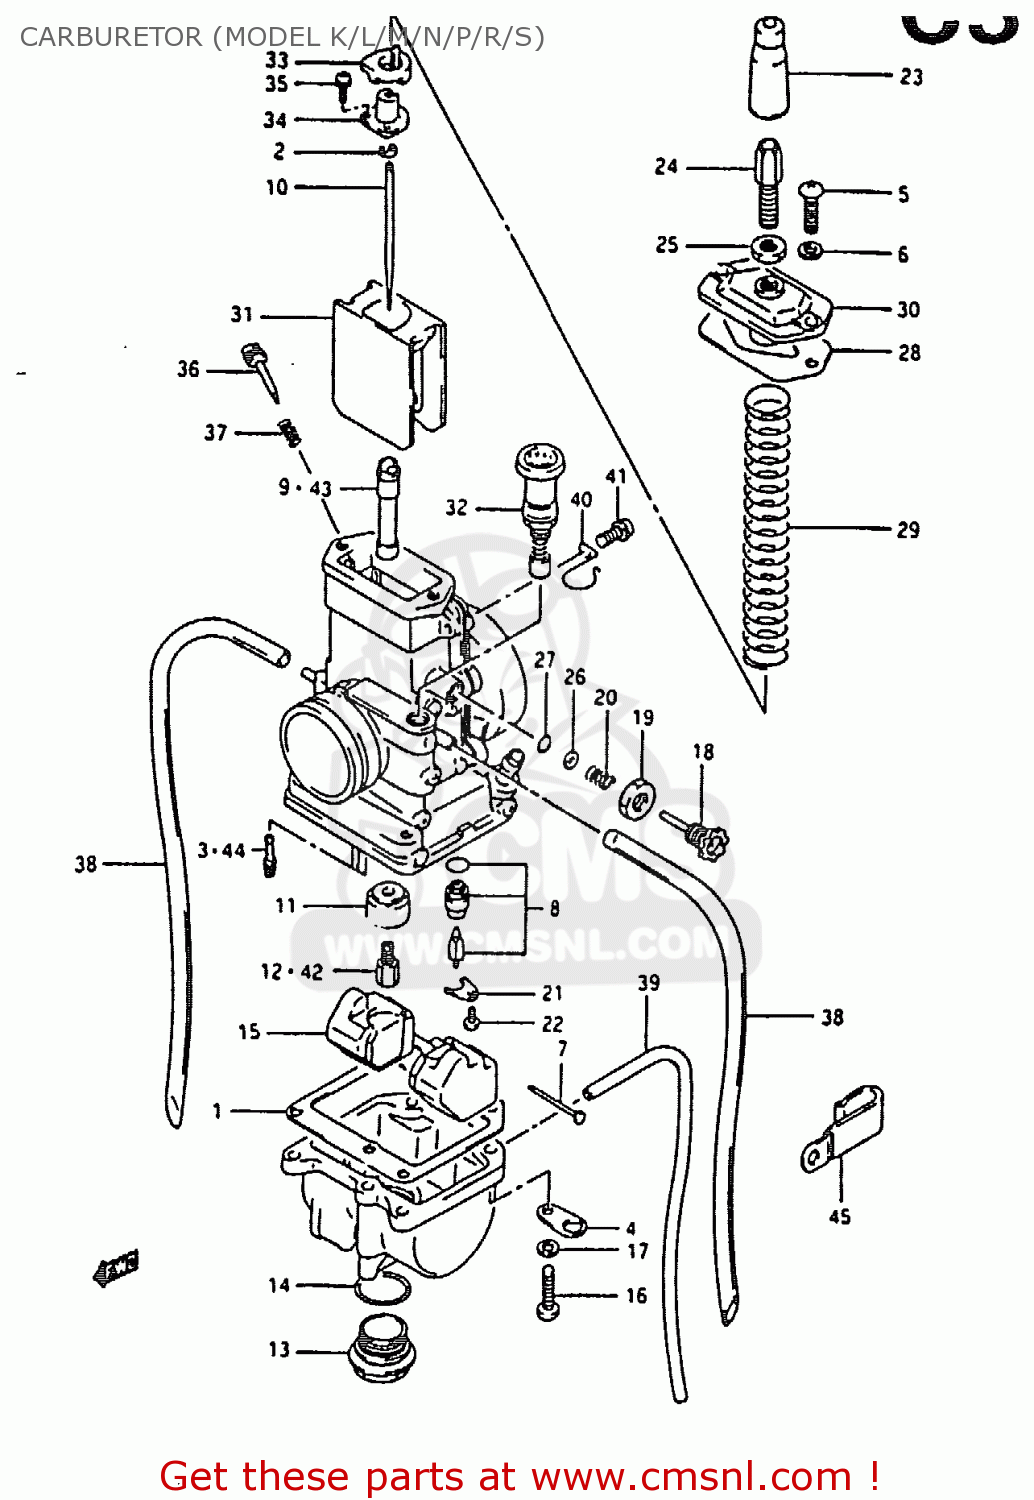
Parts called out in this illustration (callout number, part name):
1	GASKET,FLOAT CHAMBER (NAS)
2	CLIP
3	JET,PILOT(30)
4	PLATE,CARBURETOR
5	SCREW
6	WASHER,LOCK
7	PIN,FLOAT
8	VALVE ASSY,NEEDLE
9	JET,NEEDLE(P-4)
10	NEEDLE,JET(5DP39-4)
11	RING
12	JET,MAIN(200)
13	PLUG
14	O RING
15	FLOAT
16	SCREW
17	WASHER,LOCK
18	ADJUSTER,THROTTLE STOP
19	NUT
20	SPRING
21	PLATE
22	SCREW
23	CAP,CABLE ADJUSTER
24	ADJUSTER,CABLE
25	NUT
26	WASHER
27	O RING
28	GASKET,CARBURETOR TOP (NAS)
29	SPRING
30	CAP,CARBURETOR TOP
31	VALVE,THROTTLE
32	PLUNGER ASSY,STARTER
33	RING
34	JOINT
35	SCREW
36	SCREW,AIR
37	SPRING
38	HOSE
39	HOSE
40	CLIP
41	SCREW
42	JET,MAIN(170)
43	CLAMP L:35
44	JET,PILOT(25)
45	CLAMP
